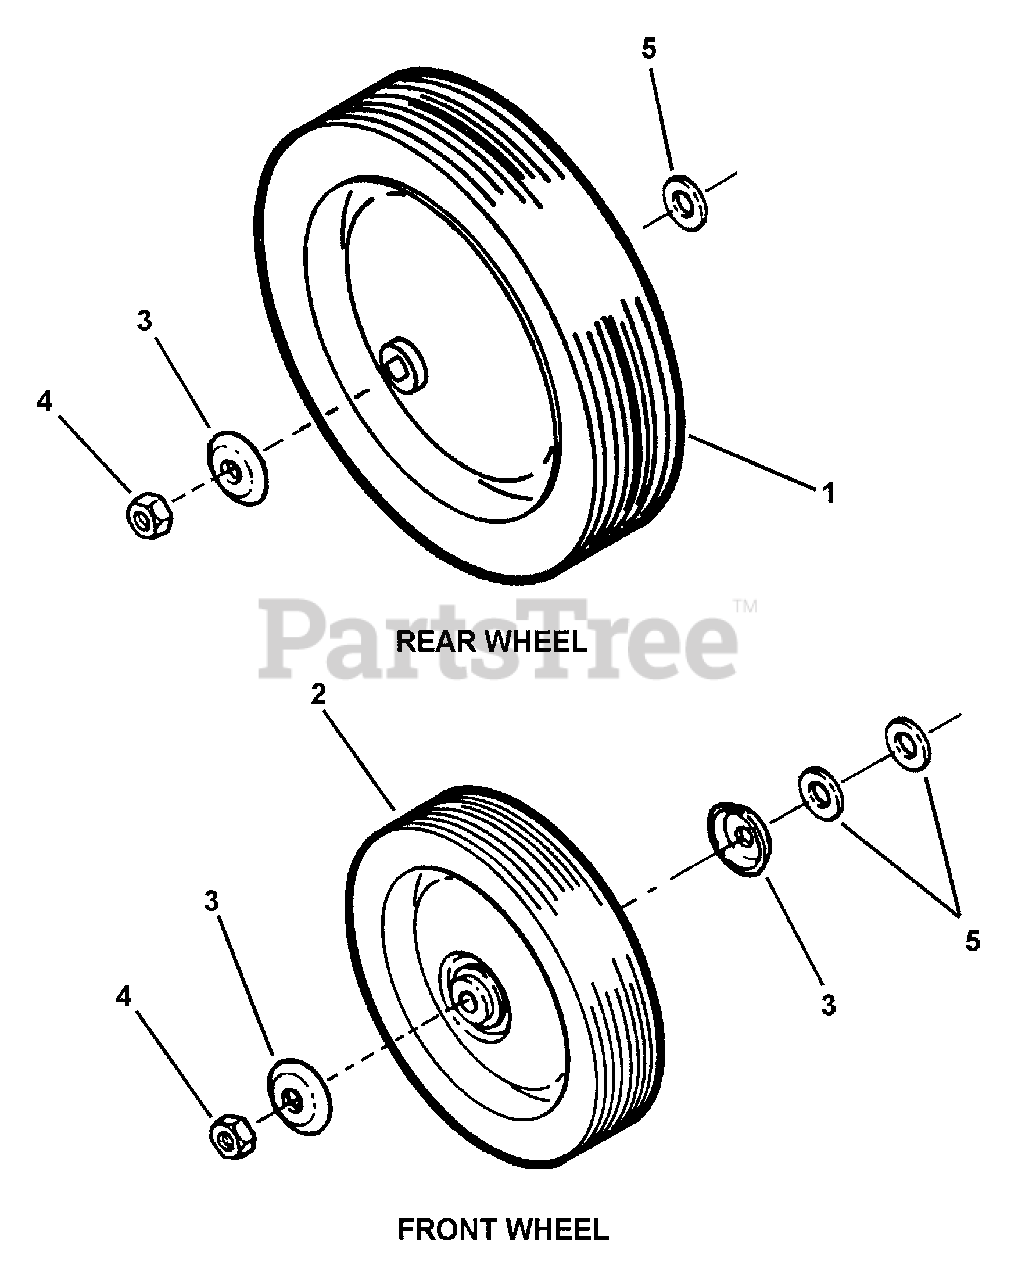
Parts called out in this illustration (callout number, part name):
1	WHEEL, Rear 10.0 x 1.75 Diamond Grey
2	WHEEL, Front 8.0 x 1.75 Diamond Black
3	HUB-CAP (Front Wheels)
4	NUT, 7/16-18 Hex Center Lock
5	WASHER, 7/16 Flat
